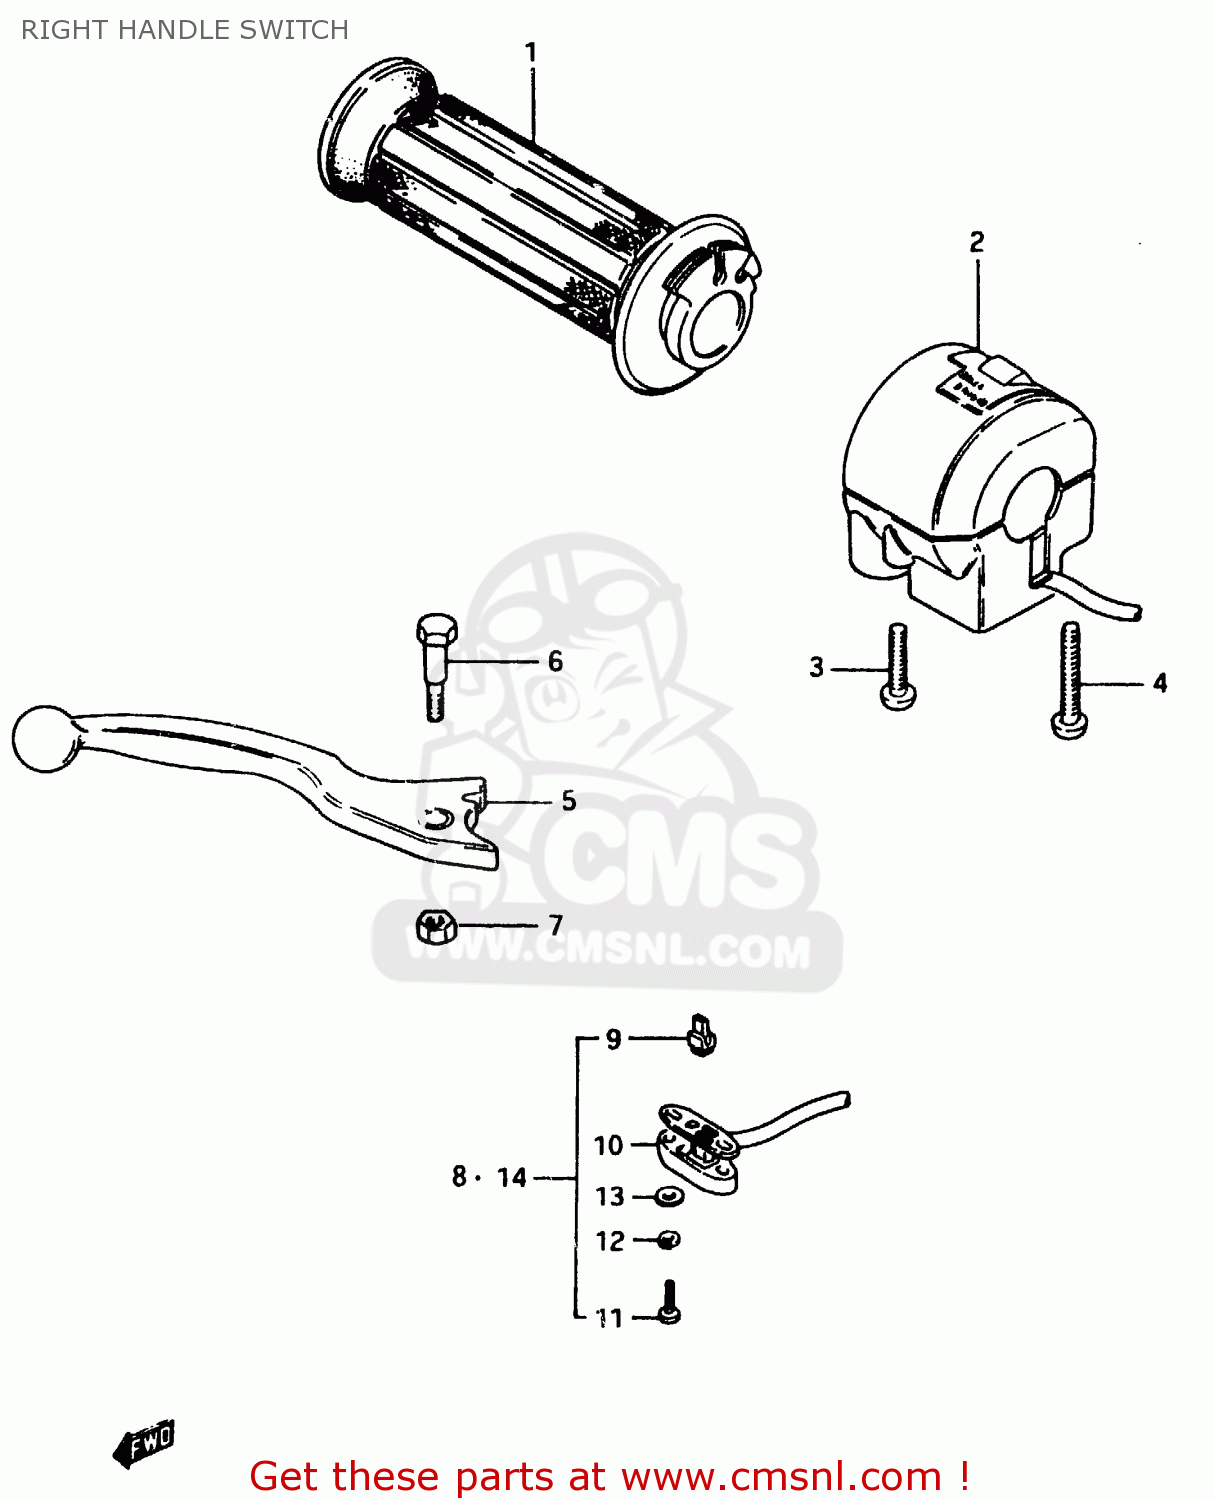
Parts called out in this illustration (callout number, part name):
1	GRIP,THROTTLE
2	SWITCH ASSY, HANDLE
3	SCREW
4	SCREW
5	LEVER,BRAKE
6	BOLT,LEVER PIVOT
7	NUT 6MM
8	SWITCH ASSEMBLY
9	CONTACT,SWITCH
10	COVER,FR BK TERMINAL BASE
11	SCREW
12	LOCK WASHER
13	WASHER
14	SWITCH ASSY,STOP
